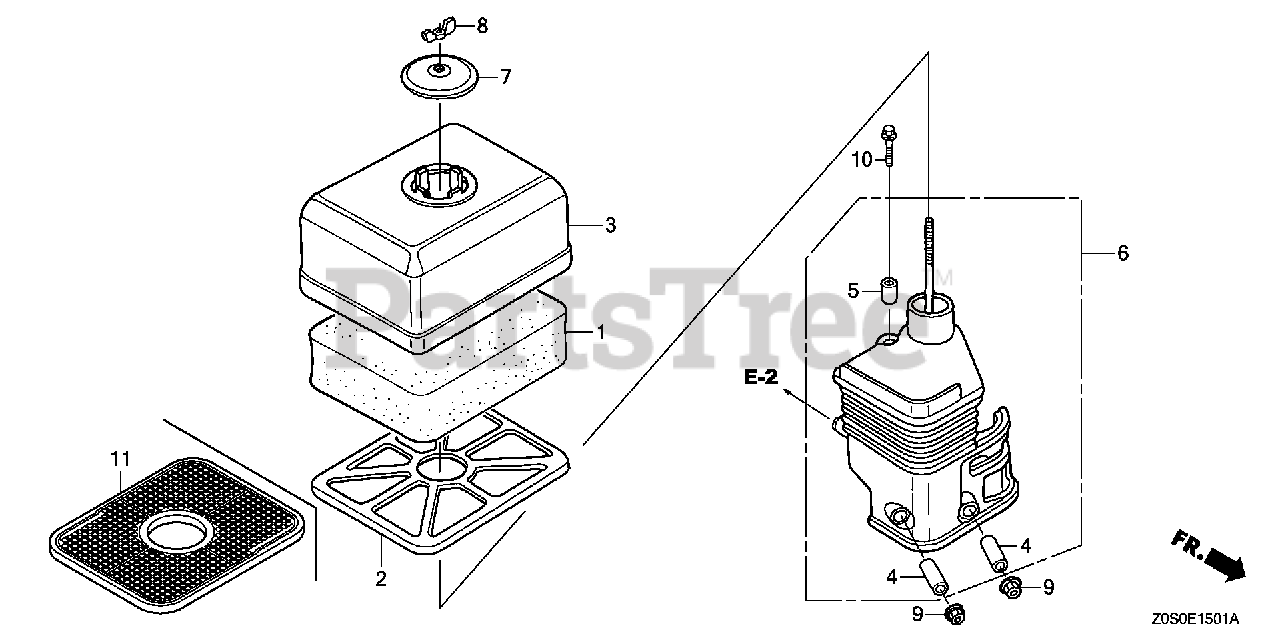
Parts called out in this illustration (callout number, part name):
1	ELEMENT, AIR CLEANER (SEMI-DRY)
2	GRID, AIR CLEANER (SEMI-DRY)
3	COVER, AIR CLEANER (SEMI-DRY)
4	COLLAR, AIR CLEANER
5	COLLAR B, AIR CLEANER
6	ELBOW, AIR CLEANER
7	CAP, CLEANER
8	NUT, TOOL BOX SETTING
9	NUT, FLANGE (6MM)
10	BOLT, FLANGE (6X20)
